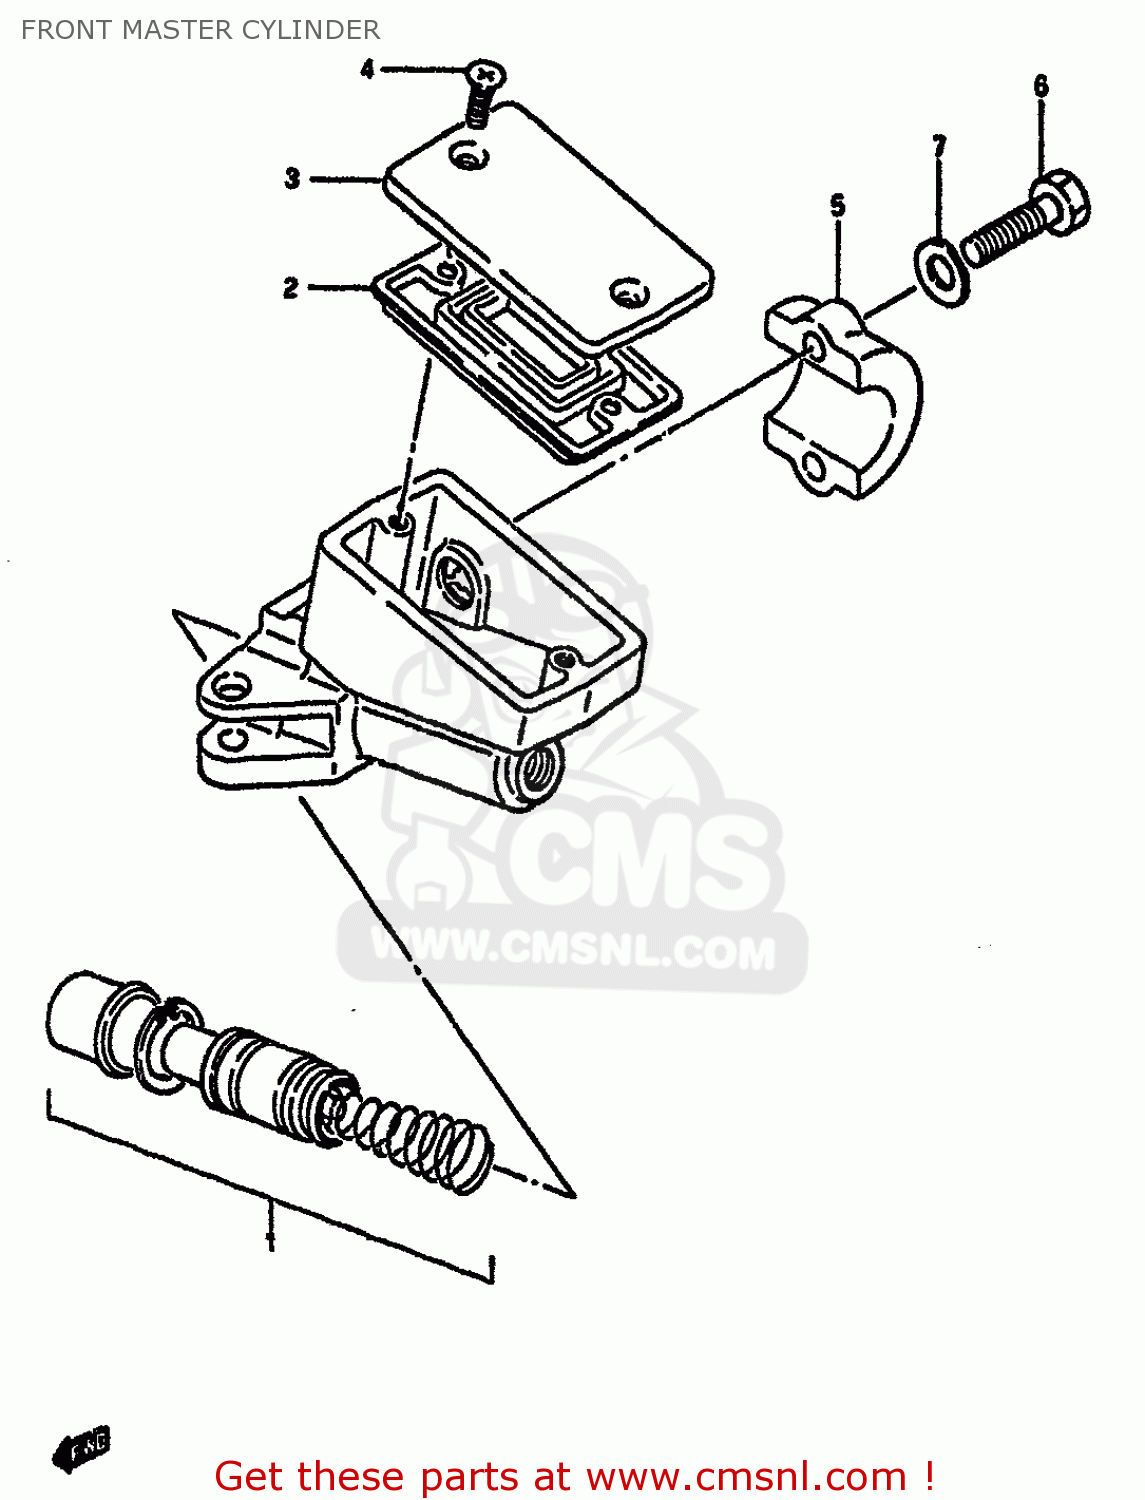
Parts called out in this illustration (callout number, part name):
1	PISTON & CUP SET
2	3
3	CAP
4	SCREW
5	HOLDER,MASTER CYLINDER
6	BOLT
7	WASHER
